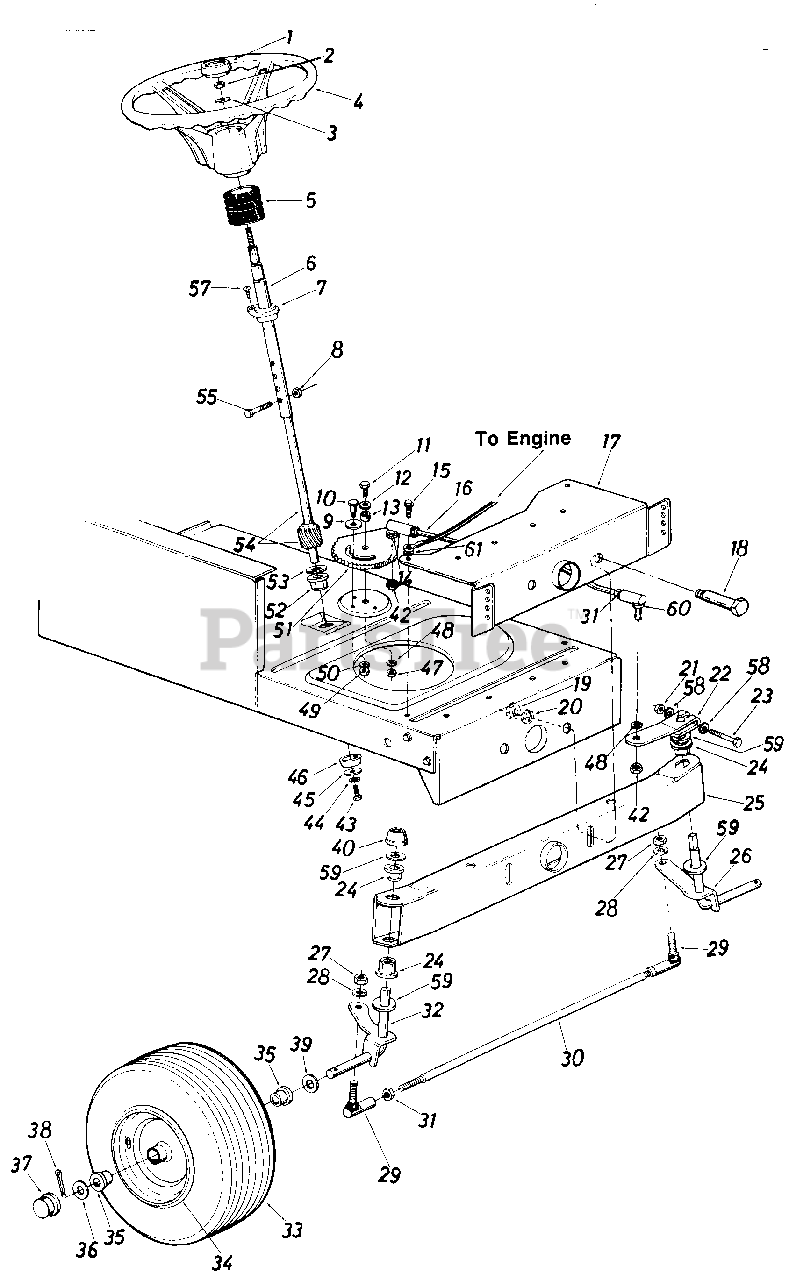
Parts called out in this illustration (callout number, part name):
1	Steering Wheel Cap
2	Hex L-Nut 5/16-24 Thd.
3	Belleville Wash. .345" I.D.
4	Steering Wheel (3 Spoke)
5	Steering Bellow-4.5"
6	Steering Column Ass'y.
7	Flange Bearing .890 I.D. x 1.36 O.D.
8	Hex L-Nut 1/4-20 Thd.
9	Fl-Wash 438" I.D. x 1.37'/ O.D.
10	Shoulder Bolt .437" Dia. x .35 Lg. 5/16-18 Thd.
11	Hex Bolt 3/8-24 x 1.0" Lg.(Grade 5)
12	Bell-Wash. .40" I.D. x 1.13" O.D.
13	Spacer .380" I.D. x .625" O.D. x .227
14	L-Wash. 3/8" I.D.
15	Hex Wash. Hd. Self-Tap Scr.
16	Steering Drag Link
17	Front Pivot Brkt.
18	Shoulder Bolt .498" Dia. x 2.04 Lg. 3/8-16 Thd.
19	Hex Nut 3/8-16 Thd.
20	L-Wash. 3/8" I.D.
21	Hex Cent. L-Nut 5/16-24 Thd.
22	Steering Arm Front Axle
23	Hex Bolt 5/16-24 x 2.00" Lg.(Grade 5)
24	Hex Flg. Brg. .634 I.D.
26	Front Axle Ass'y.-L. H .
27	Hex Nut 3/8-24 Thd.
28	L-Wash. 3/8" I.D.
29	Ball Joint 3/8-24 Thd.
30	Tie Rod
31	Hex Jam Nut 3/8-24 Thd.
32	Front Axle Ass'y.-R. H .
33	Wheel Ass'y. Comp.
34	Front Wheel Rim Only
35	Bearing
36	Fl-Wash. .635 I.D. x 1.59" O.D.
37	Front Wheel Hub Cap
38	Cotter Pin 1/8" Dia. x 1.25"
39	Fl-Wash. .640" I.D. x 1.24" O.D.
40	Push Cap 5/8" Dia. Rod
42	Hex Jam Nut 3/8-24 Thd.
43	Hex L-Bolt 5/16-18 x .62"
44	L-Wash. 5/16" I.D.
45	Fl-Wash. .33" I.D. x 1.25" O.D.
46	Spacer (Plastic)
47	Hex Nut 3/8-24 Thd.
48	L-Wash. 3/8" I.D.
49	Hex Nut 5/16-18 Thd.
50	L-Wash. 5/16" I.D.
51	Steering Gear Segment
52	Hex Flg. Brg. .634 I.D.
53	Fl-Wash. (Hardened)
54	Steering Shaft Lower
55	Hex Bolt 1/4-20 x 1.25" Lg.
57	Oval Hd. Cr.-Sunk Scr. #10 x 518" Lg.
58	Wave-Wash. .32" I.D. x .62" O.D.
59	Fl-Wash. (Hardened)
60	Drag Link Ball Joint 3/8-24 Thd.
61	Ext. L-Wash. 5/16" I.D.
